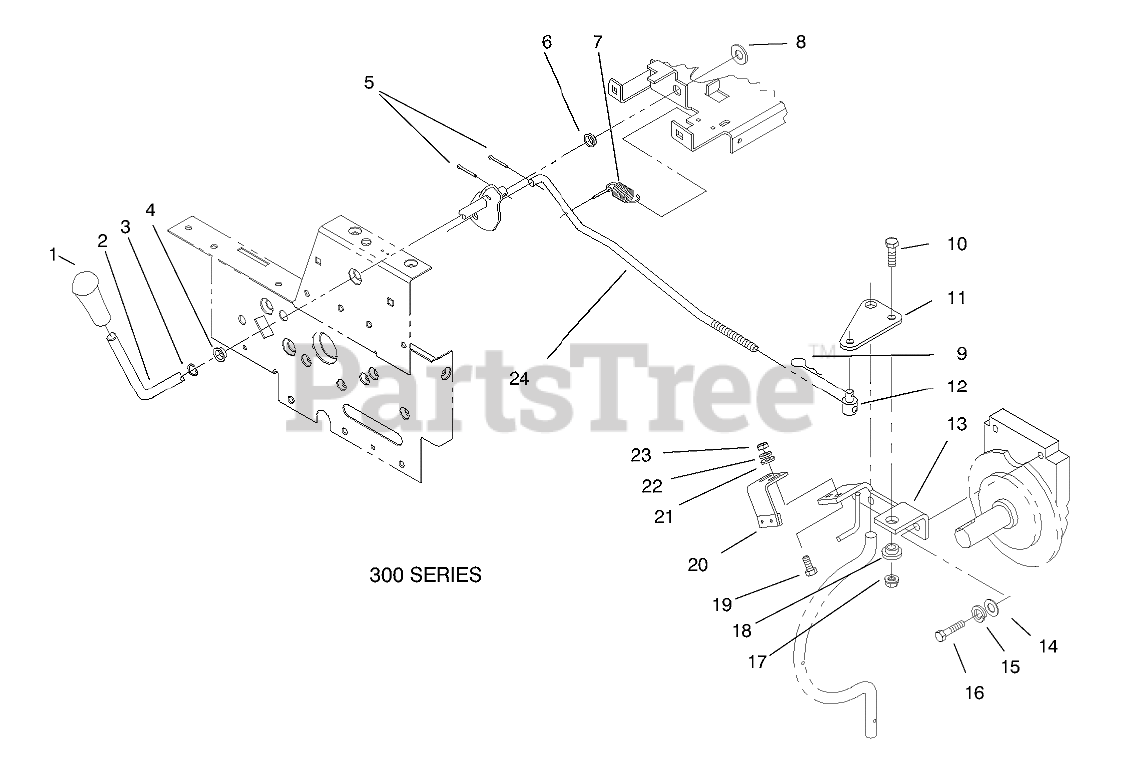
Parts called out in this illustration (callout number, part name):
2	PTO CLUTCH LEVER ASM
3	RING-EXT GRIP
4	BUSHING-NYLINER
5	PIN-COTTER
6	NYLINER BUSHING
7	SPRING
8	SHIM-WASHER
9	PIN-HAIR
10	SCREW-HH
11	PLATE
12	TRUNNION
13	ENGINE SUPT. WA (BLACK)
14	WASHER-FLAT
15	WASHER-LOCK
16	SCREW-HH
17	NUT-LOCK, NI
18	SPACER-LIFT LINK
19	SCREW-CARR
20	BRAKE ASM
21	WASHER-FLAT
22	WASHER-LOCK
23	NUT-JAM
24	ROD-PTO CLUTCH
